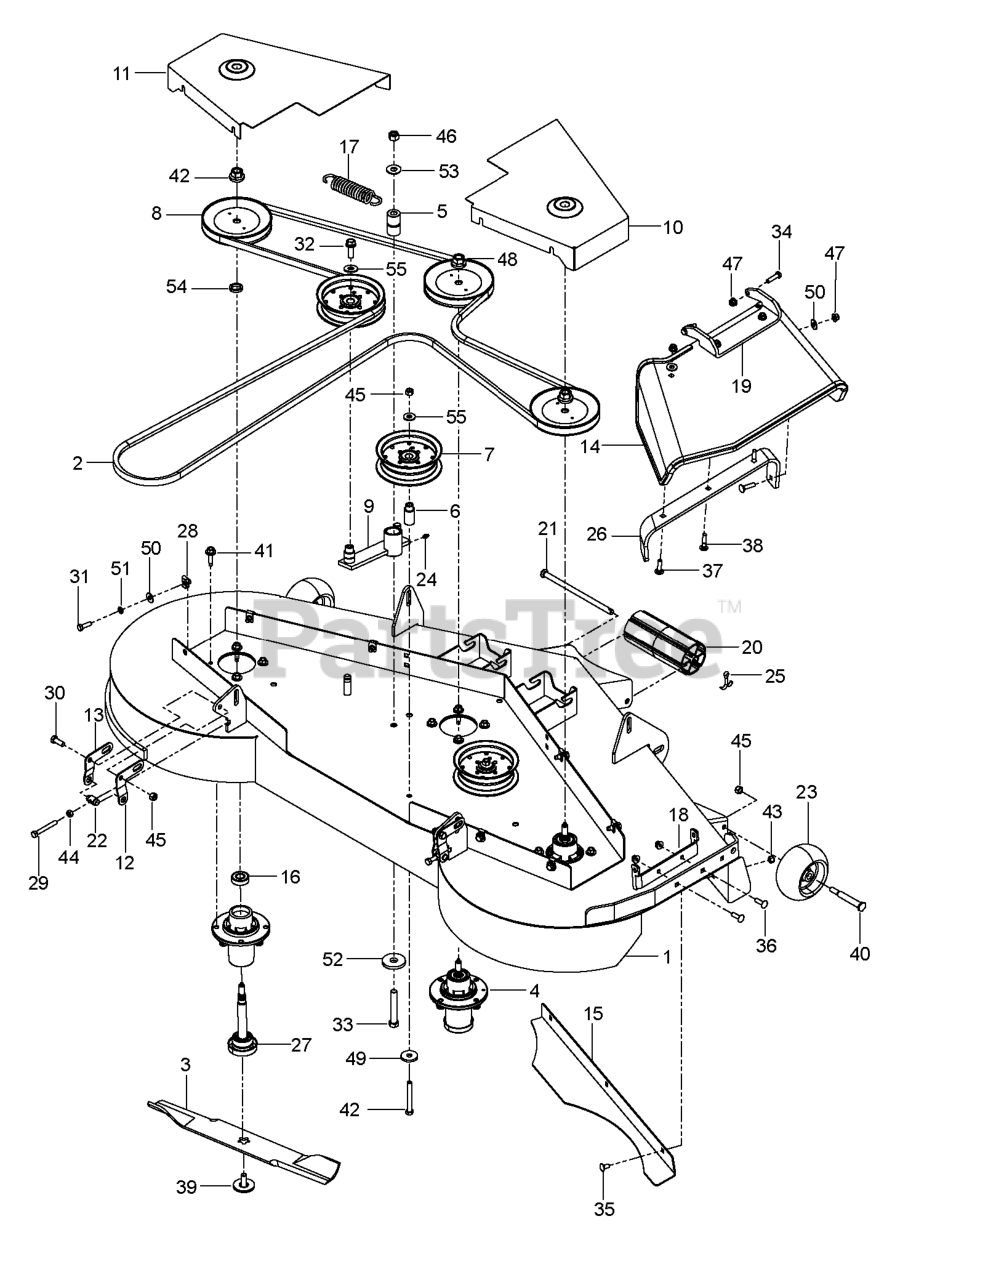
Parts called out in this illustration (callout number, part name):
1	DECK SVC MZT 61 W/DECALS ORG
2	BELT, DECK
3	BLADE, 21"
4	MANDREL ASM, CAST IRON
5	PIVOT BUSHING
6	IDLER BUSHING
7	PULLEY, IDLER
10	BELT SHIELD, RH ORANGE
11	BELT.SHIELD.LH.ORANGE
12	BRACKET.RT.PNT.MS431
13	BRACKET.LH.PNT.MS431
14	CHUTE, RUBBER DISCHARGE 52/61"
15	CONFINEMENT PLATE 61
16	BEARING, BALL
18	BRACKET.M-ZT.CHUTE(ORG)
19	PIVOT BRACKET - CHUTE
20	NOSE ROLLER 48"
21	ROD.ROLLER.NOSE.NARROW.48"
22	TRUNION, PITCH
23	WHEEL GAGE DONUT
24	ZERK
25	RP_COTTER PIN 1/8 X 3/4
26	BRKT, REINF - CHUTE 52/61"
27	SHAFT ASM MANDREL
28	U-CLIP 5/16-18 NUT RETAINER
29	HCS 5/16-18 X 2 1/2 TPBLT
30	HCS 3/8-16X1.GRD.5.ZD
31	HCS 5/16C X 3/4
32	4CS 3/8C X 1 SERRATED HEAD
33	HCS 1/2C X 3 1/4
34	HCS 5/16C X 1 1/4
35	CARRIAGE BOLT 5/16C X 5/8"
36	BOLT CRT
37	BOLT, CARRIAGE 5/16X1-1/4
38	BOLT
39	BOLT.WASHER.ASM.7/16-2
40	SHOULDER BOLT 1/2X2-5/8 ZD SPE
41	BOLT.HEX.WASHR.HED.313-18X1.19
42	LOCKNUT - 9/16
43	NUT 5/16 NYLOC
44	NUT 5/16C HEX
45	NUT
46	NUT 1/2-13 HEX NYLOC ZD
47	5/16-18 NYLOC FLANGE NUT
48	NUT.FLANGE.LOCK.TOP
49	SPINDLE WASHER
50	WASHER 5/16 FLAT
51	WASH 5/16 DISC SPRING ZD
52	WASHER, SUPPORT
53	WASHER 1/2 FLAT
54	WASHER-SPACER
55	WASHER 3/8 FLAT
